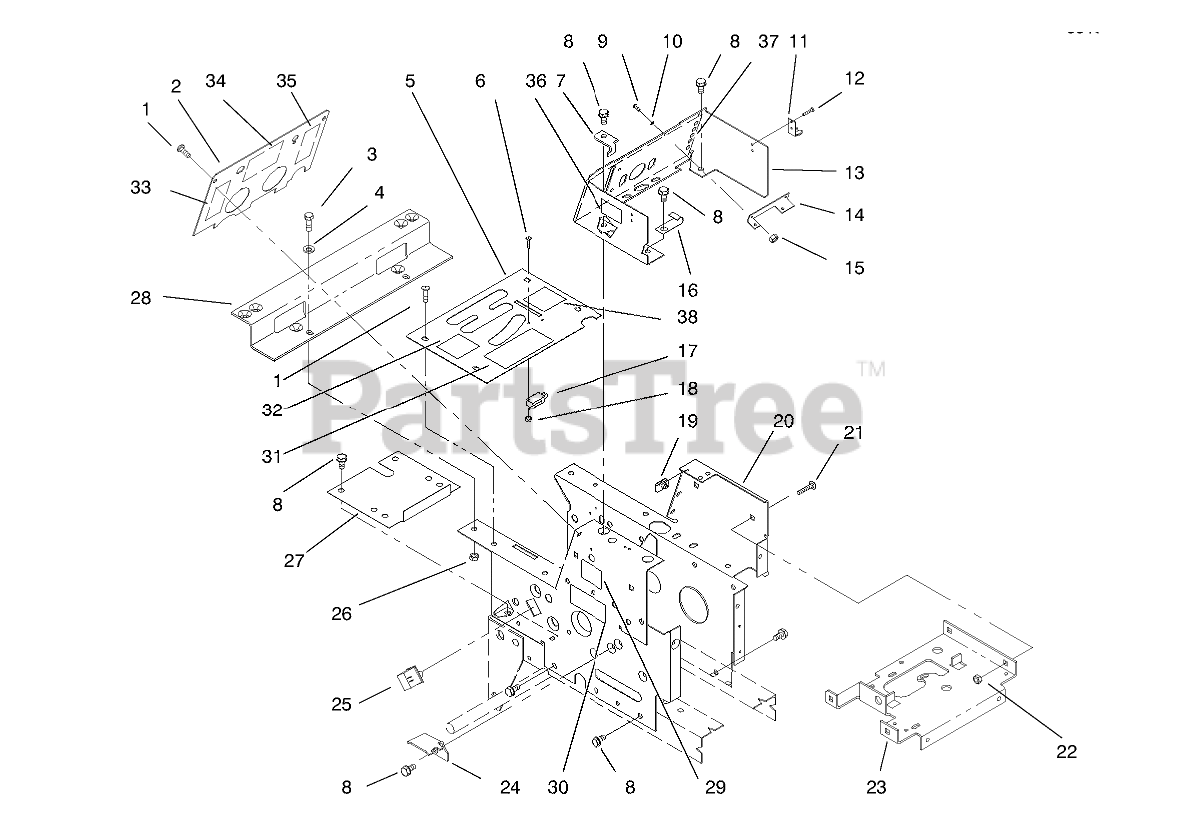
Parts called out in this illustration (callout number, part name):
1	SCREW-PPH
2	PLATE HOODSTAND (BLACK)
3	SCREW-HH
4	WASHER-PLAIN
5	Plate-Shift
6	SCREW-PPH
7	STOP-PTO
8	Bolt
9	SCREW-PAN
10	Washer-Lock
11	KEEPER-LATCH
12	RIVET-POP
13	CONSOLE (BLACK)
14	BRACKET
15	Nut
16	J-CLIP
17	SWITCH
18	NUT-HEX
20	Hoodstand
21	BOLT CARR. 5/16X1/2 BK
22	Nut
23	SUPPORT-BATTERY
24	BRACKET-BELT SUPPORT
25	SWITCH INTERLOCK
26	NUT-LOCK, NI
27	COVER-DUST
28	Bracket-Fender
30	DECAL - MODEL 314-8
31	DECAL-DANGER
32	DECAL-SHIFT PATTERN
33	DECAL PTO CLUTCH
34	DECAL-BACK PLATE
35	DECAL-LIFT
36	DECAL ELECT SYSTEM
37	DECAL-LOWER DASH
38	DECAL-PARKING, BRAKE
